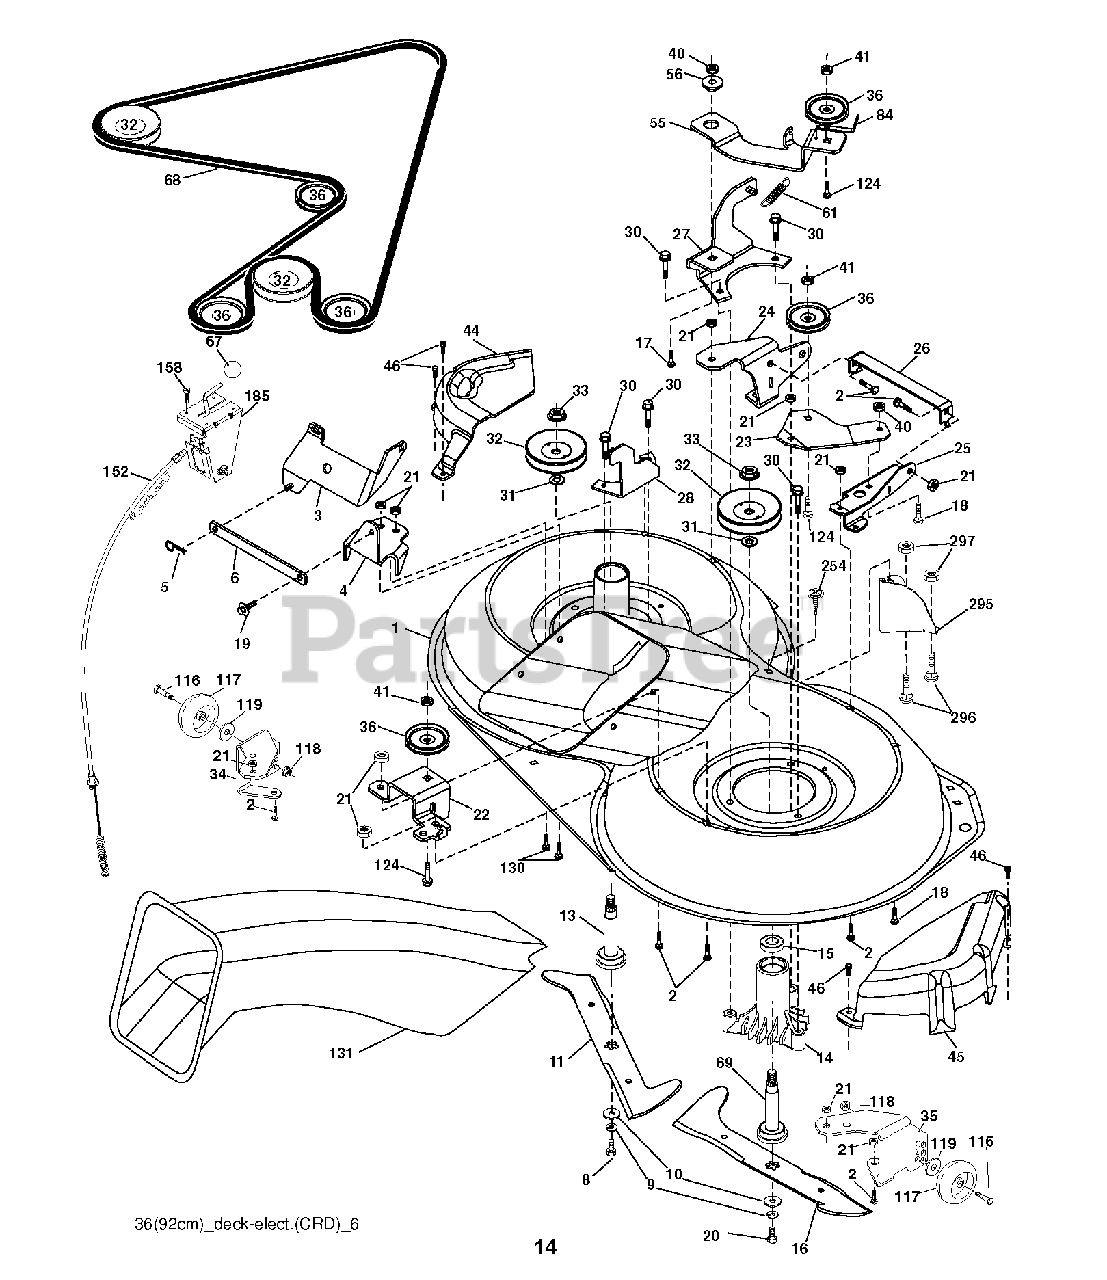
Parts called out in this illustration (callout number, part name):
2	BOLT
3	BRACKET
5	RETAINER-SPRNG RB
6	BAR SWAY
9	LOCKWASHER
10	WASHER.BLADE
13	SHAFT ASM VENT
14	HSG MANDREL
17	BOLT.3/8-14X1.25
19	BOLT SHD 5/16-18
21	LOCKNUT
24	BRACKET
25	BRACKET
28	BRACKET
30	SCREW, WASHER HEAD
31	WASHER.SPACER.MANDREL
32	PULLEY MANDREL
33	NUT.FLANGE.LOCK.TOP
36	PULLEY.IDLER.4.25
40	LOCKNUT
41	NUT LOCK FLG 3/8-16 UNC
45	MANDREL COVER
46	SCREW.1/4-20X5/8
56	SPACER.RETAINER.MOWER
67	KNOB T (3/8 HOLE)
69	SHAFT.ASM.W/LWR.BRG.RH.THREAD
84	KEEPER, BELT IDLER
116	BOLT.SHOULDER.3/8-16X3-5/8
117	WHEEL. GUAGE RALLY
118	NUT LOCK FLG 3/8-16 UNC
124	BOLT.3/8-16X1.50
131	CHUTE BAGGER
158	SCREW
185	HEAD ASM. CABLE CLUTCH
254	SCREW 3/8-16X1
296	BOLT
297	NUT CENTERLOCK
